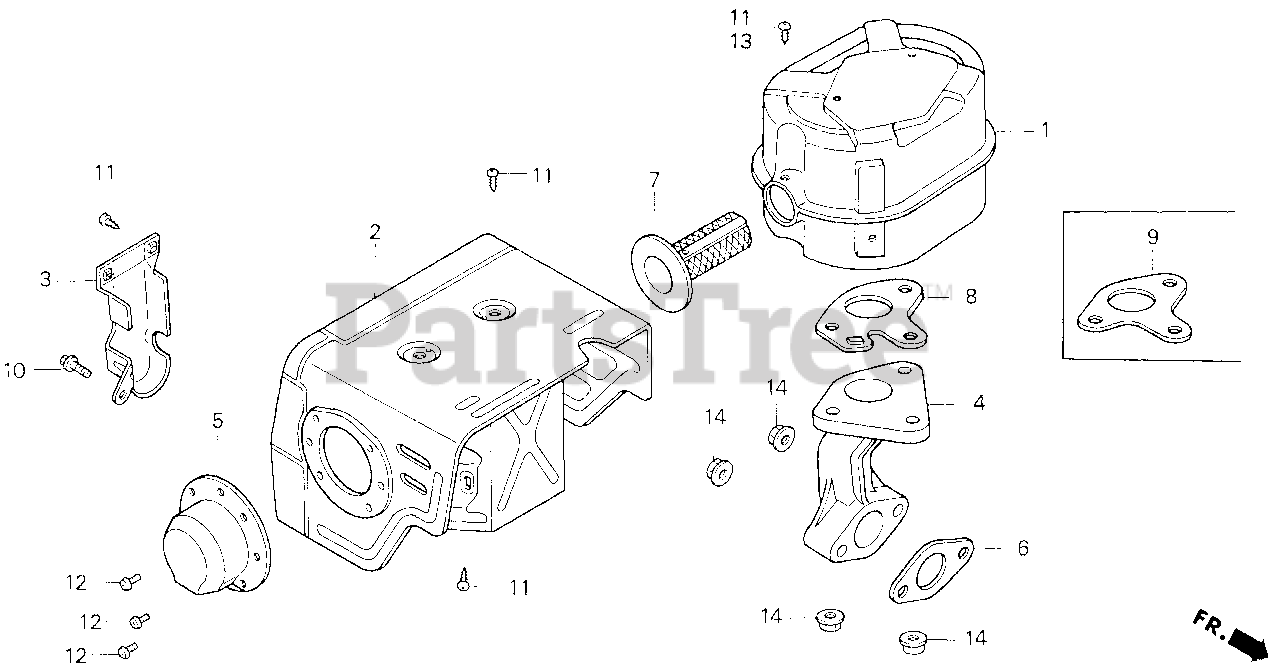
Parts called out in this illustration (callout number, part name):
1	MUFFLER
2	PROTECTOR, MUFFLER
3	PROTECTOR, EX. PIPE
4	PIPE, EX.
5	CAP, MUFFLER
6	GASKET, EX. PIPE
6	GASKET, EX. PIPE (WACKER)
7	ARRESTER, SPARK
8	GASKET, MUFFLER (ARRESTER)
10	BOLT, FLANGE (6X12) (CT200)
11	SCREW, TAPPING (5X8)
12	SCREW, TAPPING (4X6)
14	NUT, FLANGE (8MM)
